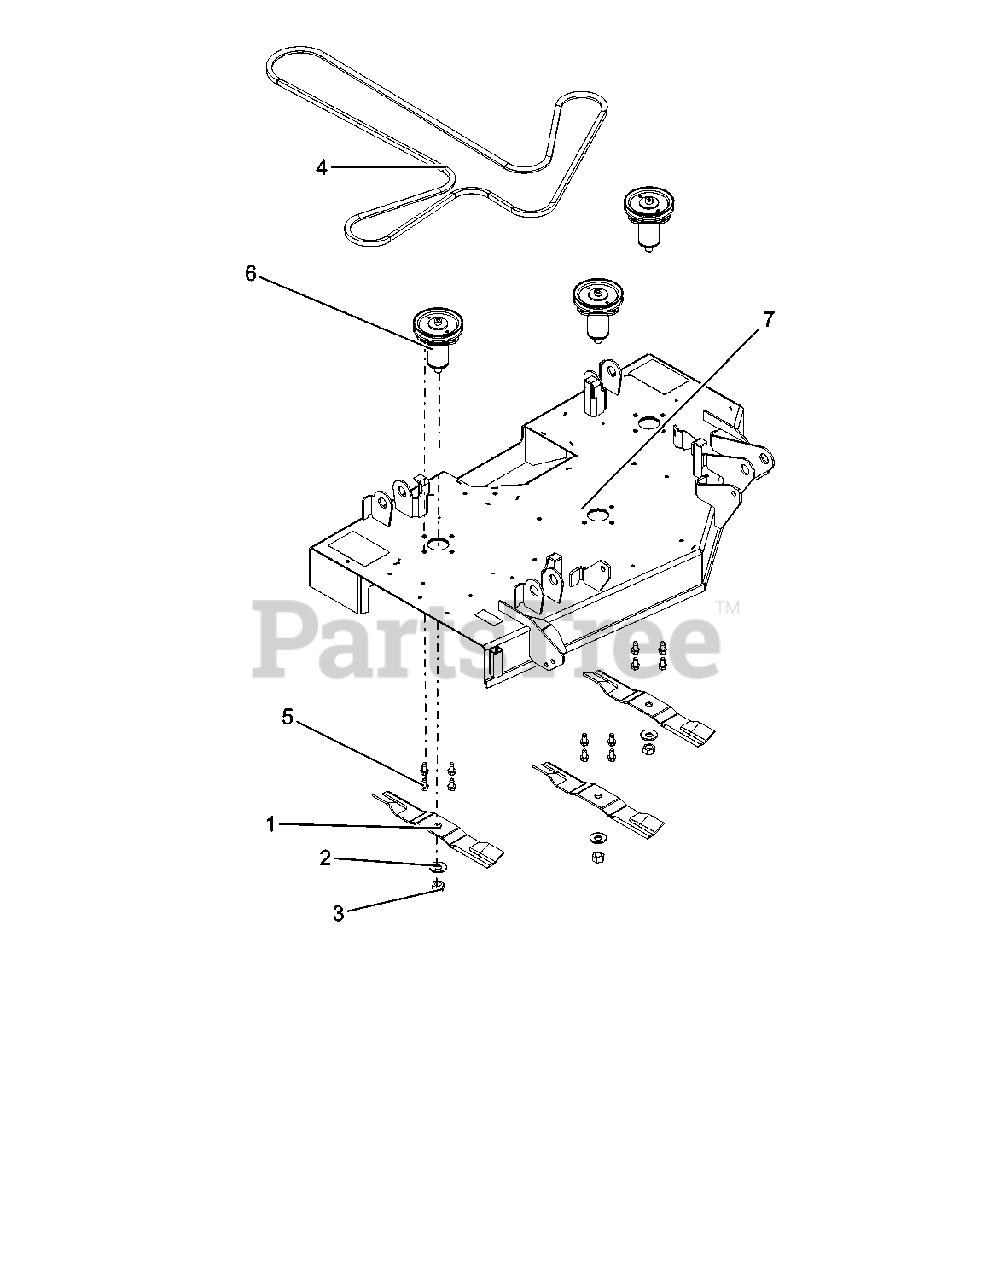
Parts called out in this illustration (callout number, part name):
1	BLADE, MOWER 15.00" LG
2	WSHR, BLVL-.63X1.625X.14
3	NUT-HEX .62-18 YWZC
4	V-Belt, HA-WRAPPED CLUTCHING (NO RUBBER BLEED THRU)
5	SCR-TAP .38-16X.75 HWH TR YWZ
6	ASM, SPINDLE 4.75" DIA.
7	WLDMT, DECK 42" (RED)
